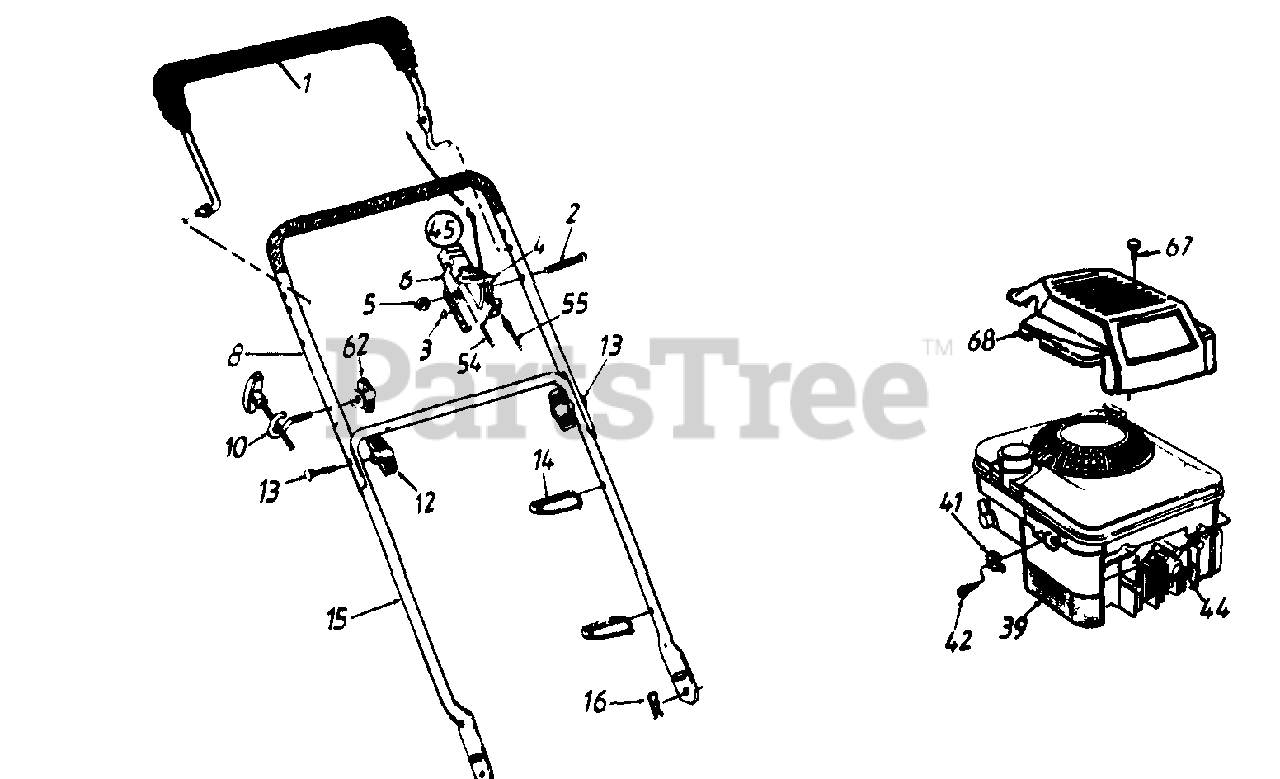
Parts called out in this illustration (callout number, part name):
1	Control Handle Ass'y.
2	Oval C-Sunk Scr.
3	Spr. Wash..66" I.D.
4	Throttle Lever
5	Hex L-Nut 1/4-20 Thd.
6	Throttle Body
12	Hand Knob
13	Curved Hd. Bolt 5/16-18 x 2" Lg.
14	Cable Tie
16	Hairpin Cotter
39	Engine
41	Cable Clamp
42	Hex Self-Tap Scr. #10-32 x .62"
44	Spark Plug Boot
45	Throttle Box Comp.
54	Throttle Cable - 51" Lg.
55	Control Cable - 36" Lg.
62	Handle Knob 1/4-20 Thd.
67	Hi-Lo Scr. #10 x 1.25" Lg. (108R)
68	Engine Shroud (108R)
